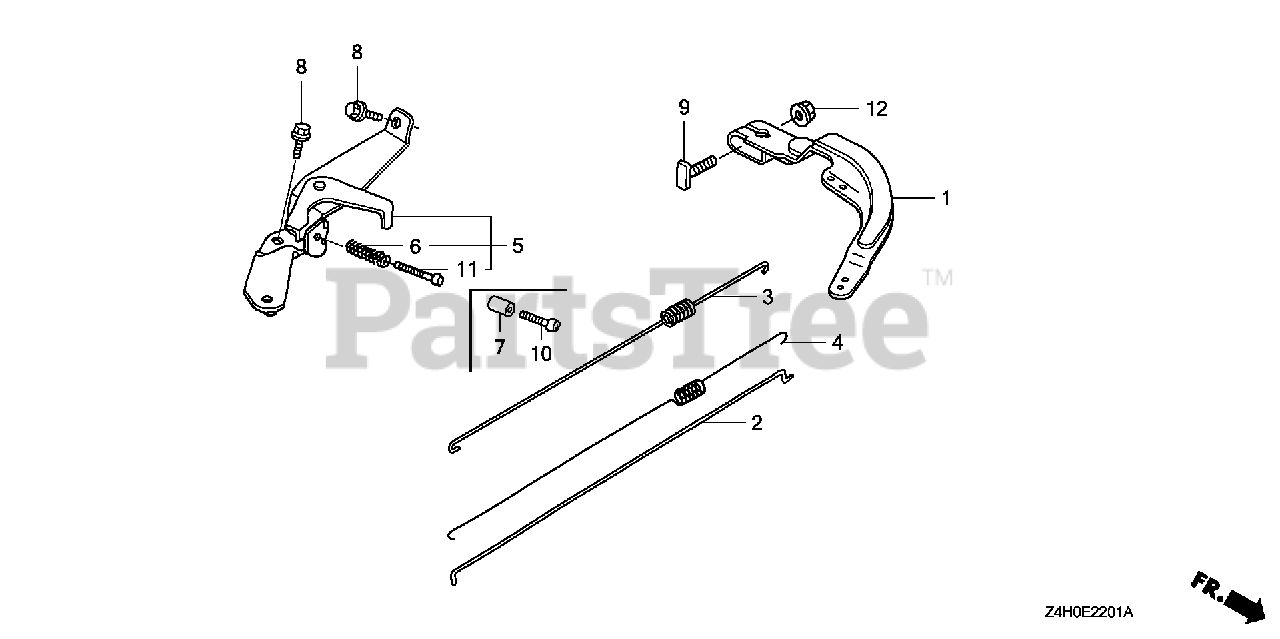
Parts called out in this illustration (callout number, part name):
1	ARM, GOVERNOR
2	ROD, GOVERNOR
3	SPRING, GOVERNOR
4	SPRING, THROTTLE RETURN
5	CONTROL ASSY.
6	SPRING, CONTROL ADJUSTING Use from Engine SN 2327377.
8	BOLT, FLANGE (6X12) (CT200)
9	BOLT, GOVERNOR ARM
11	SCREW, PAN (5X35)
12	NUT, FLANGE (6MM)
